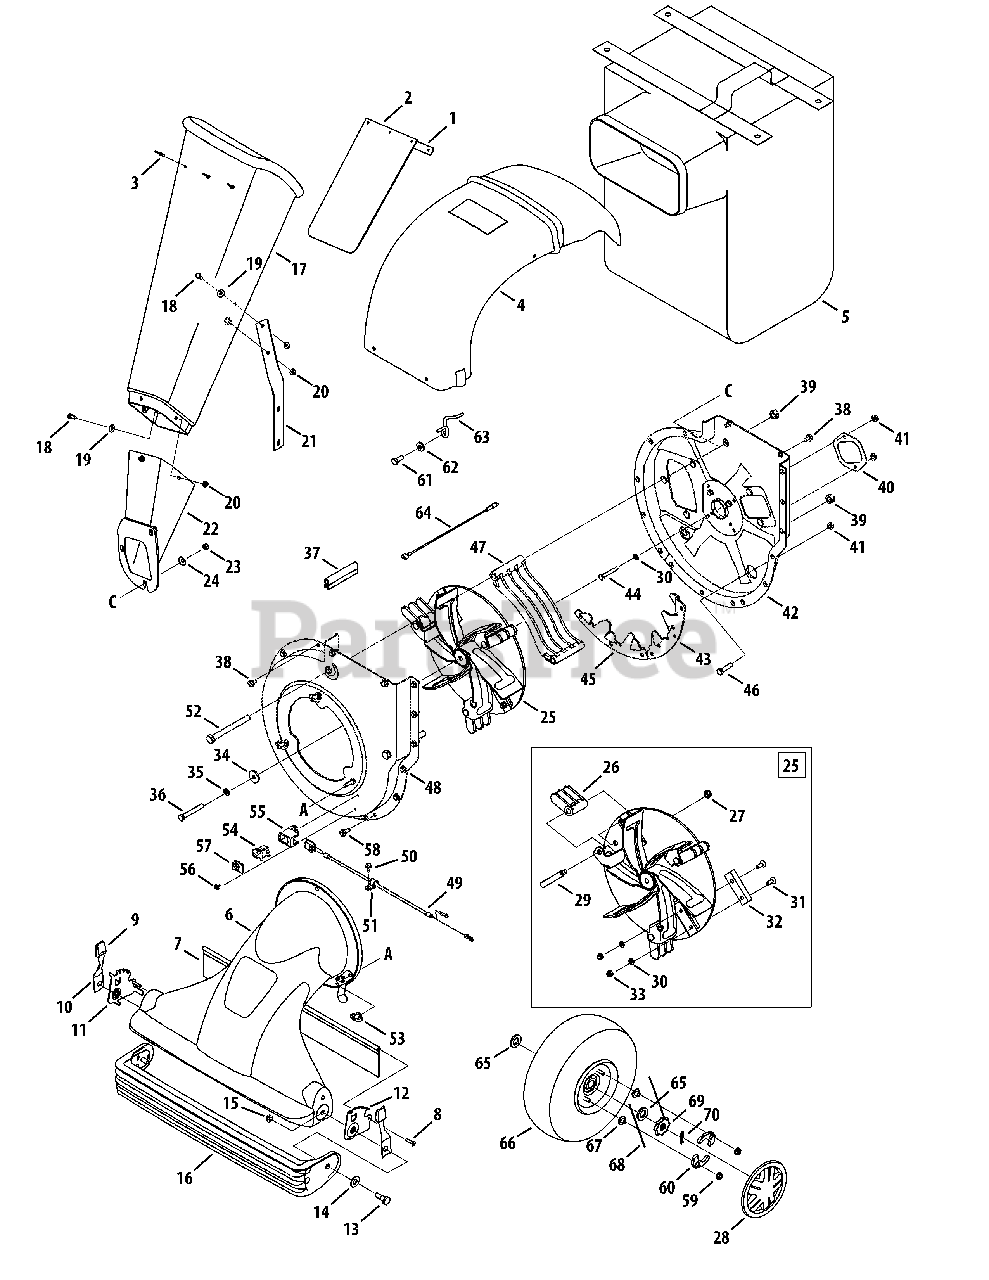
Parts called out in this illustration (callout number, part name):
1	Chute Flap Strip
2	Chute Flap
3	Pop Rivet
4	Discharge Chute
6	Nozzle Assembly
7	Nozzle Flap
9	Height Adjustment Knob
10	Spring Lever
11	Index Bracket RH
12	Index Bracket LH
13	Shoulder Screw
14	Flat Washer, .510 x 1.12 x.060
15	Hex Flange Lock Nut, 3/8-16
16	Door Assembly
17	Chipper Chute
18	Hex Cap Screw, 1/4-20 x.620
19	Flat Washer, .28 ID x.74 OD
20	Hex Lock Nut, 1/4-20
21	Support Bracket
22	Chipper Chute Assembly
23	Hex Nut, 5/16-18
24	Bell Washer, .340ID x.872OD
25	Impeller Assembly: Complete
26	Flail Blade
27	Jam Lock Nut, 3/8-16
29	Shoulder Pin, .5 x 2.625
30	Lock Washer, 5/16
31	Cap Screw 5/16-24 x 1.0
32	Chipper Blade
33	Hex Lock Nut 5/16-24
34	Flat Washer, .406 x 1/1/4
35	Lock Washer, 3/8
36	Hex Cap Screw, 3/8-24 x 2.75
37	Rubber Seal
38	Hex Washer Screw, 5/16-18
39	Hex Lock Nut, 1/2-13
40	Chipper Blade Cover
41	Hex Flange Lock Nut 5/16-18
42	Housing Assembly: Inner Flail
43	Upper Shredder Blade
44	Hex Cap Screw, 5/16-18 x 2
45	Flail Housing Blade
46	Hex Cap Screw, 5/16-18 x.75
47	Discharge Screen
48	Housing Assembly: Outer Flail
49	Wire Harness
50	TT Screw, 1/4-14 x 0.625"
52	Hex Cap Screw, 1/2-13 x 5.0
53	Knob, 5/16-18
55	Safety Switch Mounting Cover
56	Hex Washer Screw
57	Switch Cover
58	LD Screw, 5/16-18 x 0.75"
59	Hex Flanged Lock Nut, 1/4-20
60	Pawl, .345 ID -LH
60	Pawl, .345 ID - RH
61	Hex Cap Screw, 5/16-24 x.75
62	Flat Washer, .344 x.75 x.12
63	Belt Keeper
64	Adapter Harness Assembly
65	Flat Washer, 5/8 ID x 1.0 OD
66	Wheel Complete 10 x 4 x 4
67	Hex Nut, 1/4-20
68	Plastic Spring Ratchet
69	Wheel Ratchet 1.62 OD x.5 serr
70	Cotter Pin
